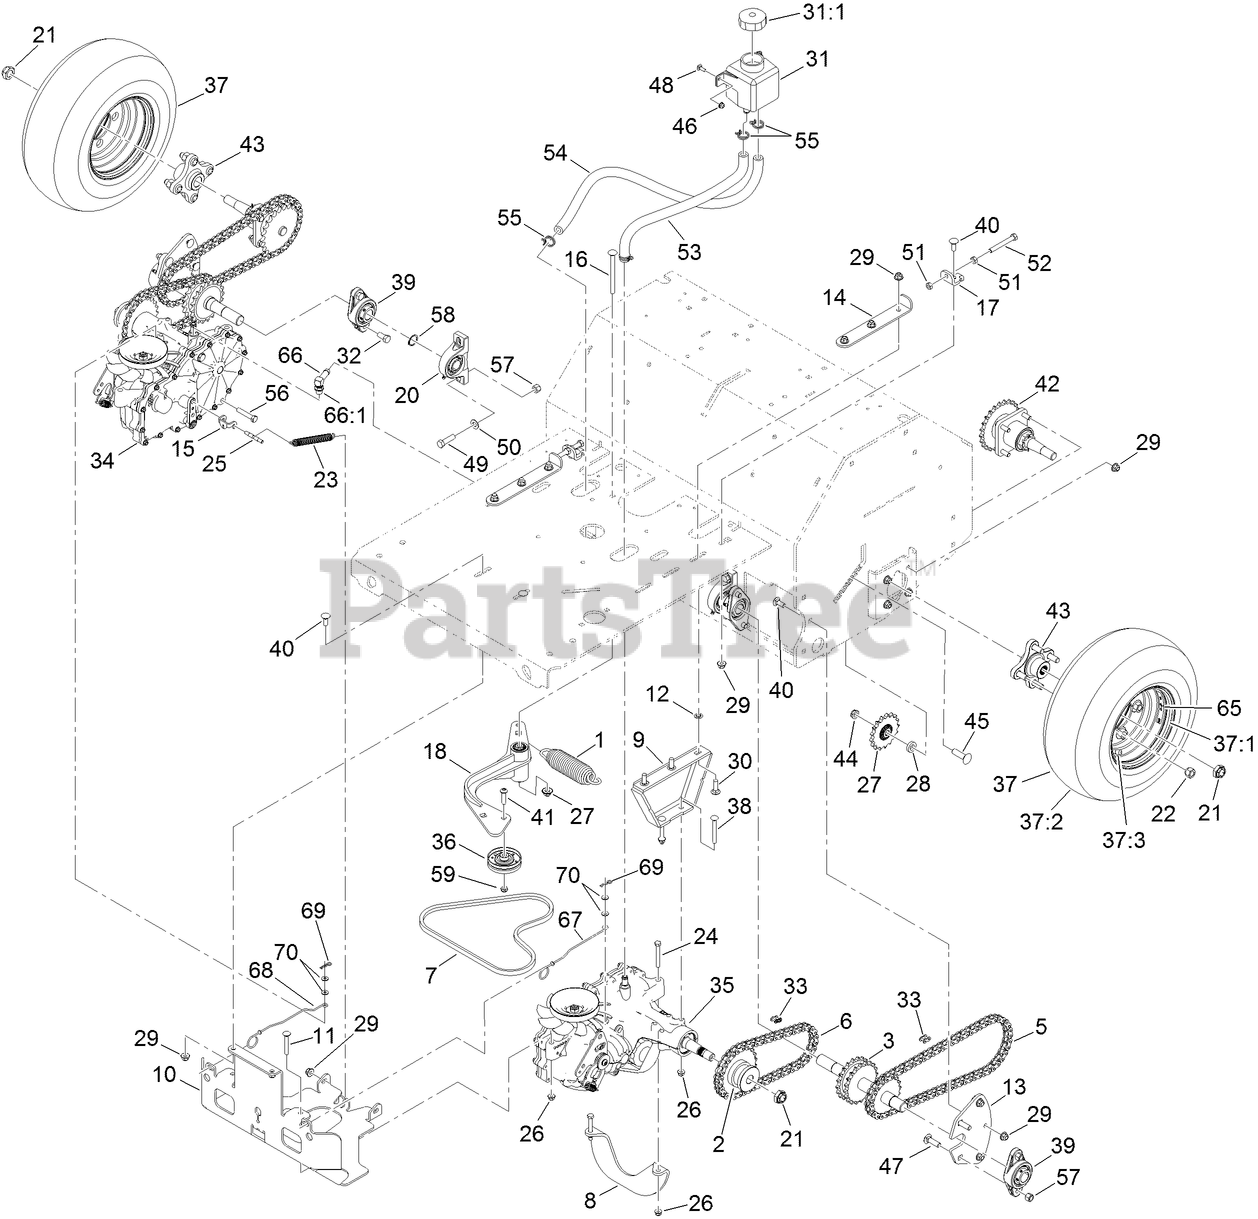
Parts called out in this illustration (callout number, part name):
1	SPRING-EXTENSION
2	HUB-DRIVE, CHAIN
3	JACKSHAFT
5	CHAIN-ROLLER
6	CHAIN-ROLLER
7	BELT-4L SECTION
8	BRACE-ANGLE
9	MOUNT-TRANSMISSION
10	GUARD-TRANSMISSION
11	BOLT-CARR
12	NUT-PUSH
13	PLATE-JACKSHAFT
14	PLATE-ADJUSTMENT, TRANSMISSION
15	YOKE-BRAKE, PARK
16	BOLT-CARR
17	BRACKET-HYDRO, ADJUST
18	IDLER ARM ASM
20	BEARING-PILLOW BLOCK
21	NUT-LOCK
22	NUT-LUG
23	SPRING-DOOR
24	SCREW-HH
25	PIN-BRAKE, PARK
26	NUT-HF, NI
27	SPROCKET-IDLER, 15T
28	WASHER
29	NUT-HF, NI
30	BOLT-CARR
31	TANK-HYD
31:1	CAP-RESERVOIR, HYD
32	SCREW-HH
33	LINK-CONNECTING
34	RH TRANSAXLE ASM (W/PIN)
35	LH TRANSAXLE ASM (W/PIN)
36	PULLEY-IDLER
37	WHEEL AND TIRE ASM
37:1	RIM-GRAY
38	SCREW-CARR
39	BEARING-FLANGE, 2 BOLT
40	BOLT-CARR
41	SCREW-HSBH
42	AXLE AND BEARING ASM
43	HUB-OFFSET
44	NUT-HEX
45	SCREW-CARR
46	NUT-HF
47	BOLT-CARR
48	BOLT-CARR
49	SCREW-HH
50	WASHER-FLAT
51	NUT-HEX
52	SCREW-HH
53	HOSE-HYDRAULIC
54	HOSE-HYDRAULIC
55	CLAMP-HOSE
56	SCREW-HH
57	NUT-LOCK, NI
58	RING-RETAINING
65	DECAL-HUB, WHEEL
66	FITTING-ELBOW, 90
66:1	O-RING
67	ROD-BYPASS, RH
68	ROD-BYPASS, LH
69	PIN-COTTER
70	WASHER
